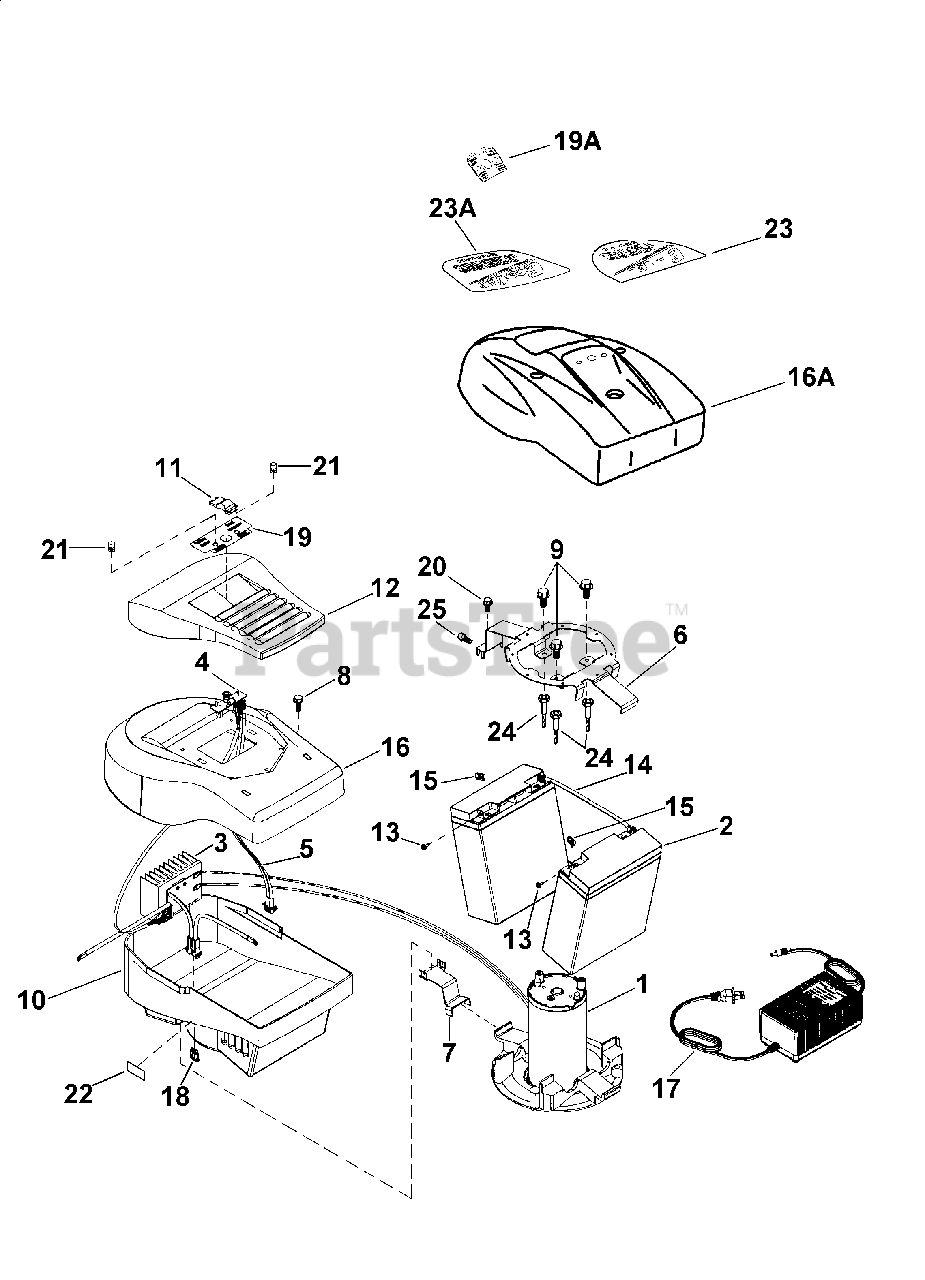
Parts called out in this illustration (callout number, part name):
1	"Electric Motor
2	Battery Assy (Incl. 13 & 15)
3	Circuit Board (Mother)
4	Circuit Board (Daughter)
5	Lead Wire (Bail)
6	Battery Support Bracket
7	Heat Sink Bracket
8	Screw, 10-24 x 9/16"
9	Screw 1/4-20 x 1/2"
10	Battery Cover
11	Charger Port Cover
12	Motor Grill
13	Screw 10-16 x 1/2"
14	Lead Wire (Battery)
16	Motor Shroud
17	Battery Charger (230 Volt)
18	Fuse (40 Amp)
19	LED Decal
20	Screw 8-32 x 27/64"
21	LED Lens Cap
22	Fuse Decal
23	Rechargeable Decal (Craftsman)
25	Screw 10-32 x 1/2"
